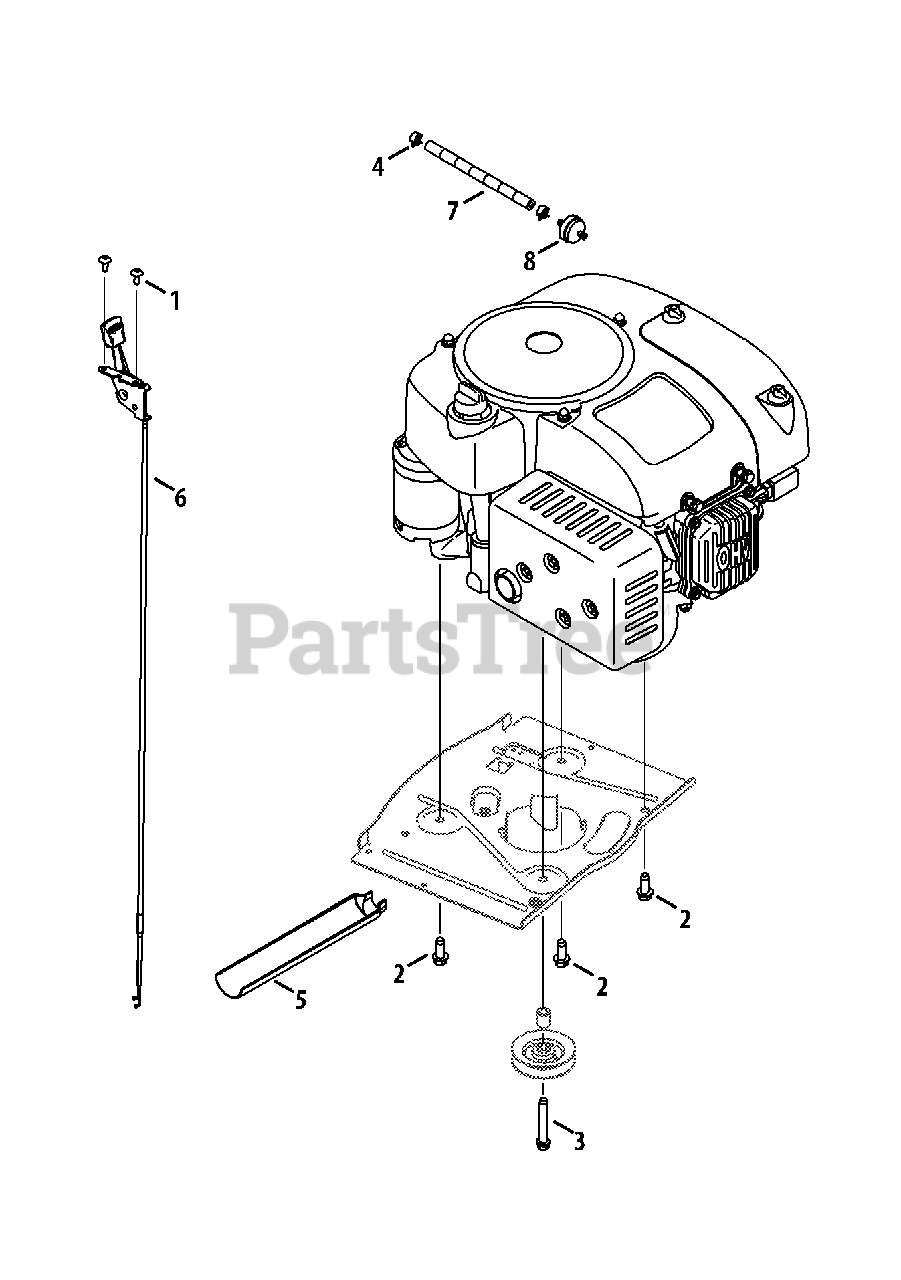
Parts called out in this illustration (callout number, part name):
1	Tap Screw, 1/4-20, 0.500
2	Tap Screw, 3/8-16, 1.000
3	Tap Screw, 3/8-16, 2.250
4	Hose Clamp, .490 DIA.
5	Oil Drain Sleeve
6	Throttle/Choke Cable 31 Lg.
7	Low Permeation Fuel Line, 1/4
8	Fuel Filter, 1/4"
